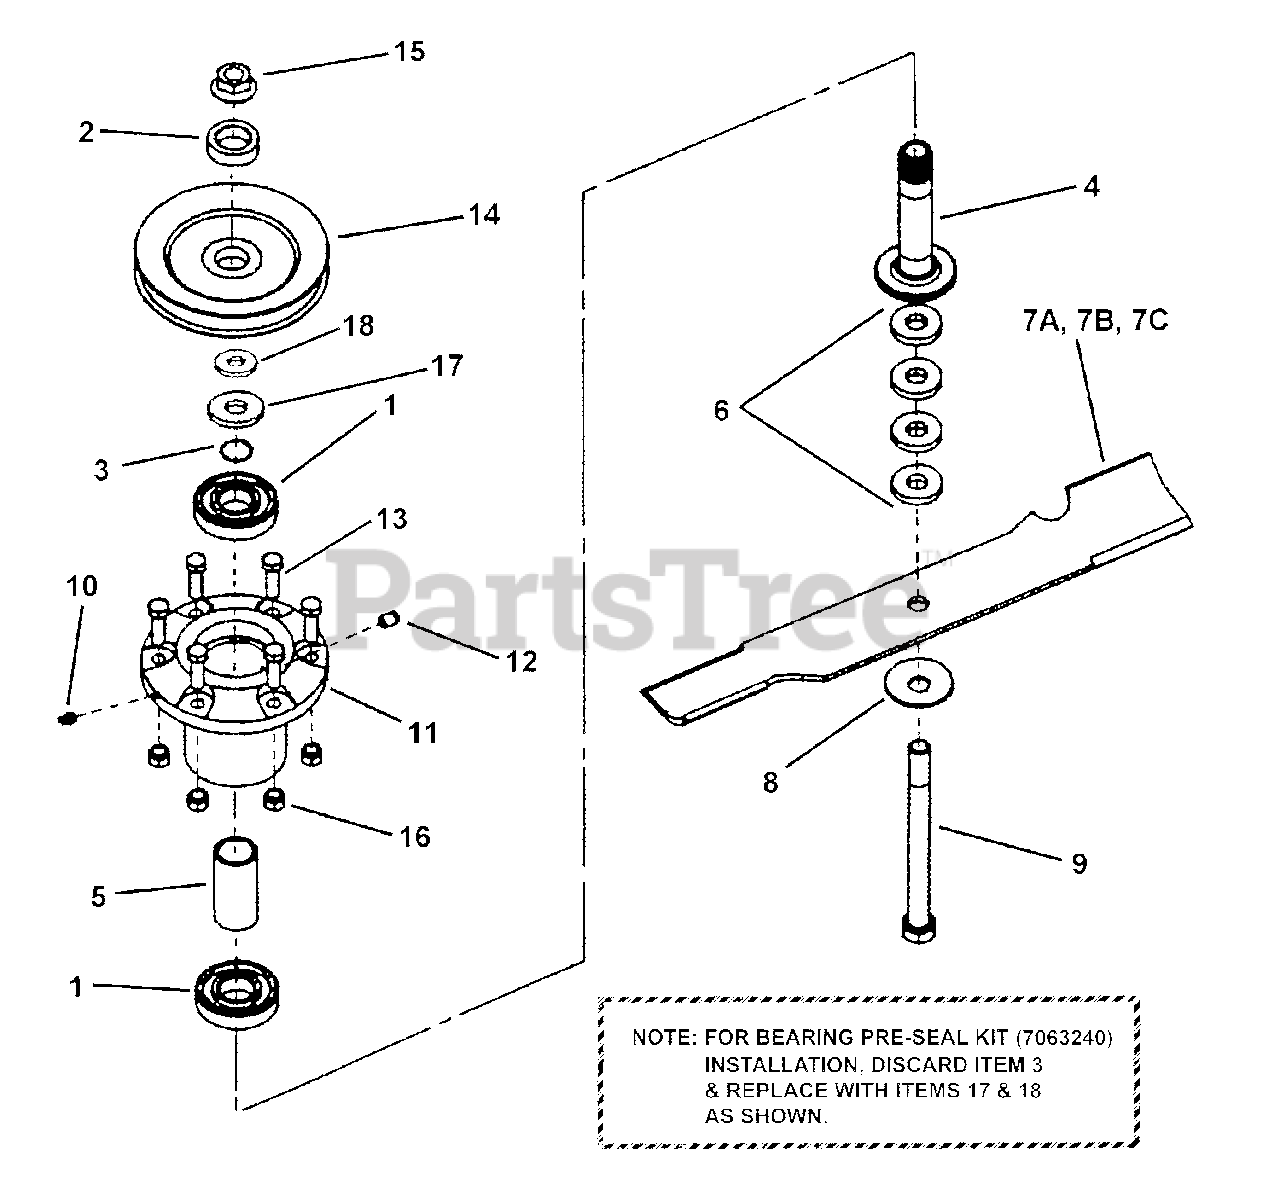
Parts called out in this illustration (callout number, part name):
1	BEARING, Sealed
2	WASHER, Spindle
3	SNAP-RING, Spindle Shaft
4	ASSEMBLY, Spindle Shaft
5	SPACER, Bearing
6	SPACER, Blade
7A	BLADE, Commercial, 18" Low Lift
7B	BLADE, 21" Low Lift
7C	BLADE, 16-1/2"
8	WASHER, Beveled
9	BOLT, 5/8-18 x 7-1/2" Hex Head Cap, GR 5
10	LUBE FITTING, 1/4-28 Straight (Thread Forming)
11	* HOUSING, Cutter
12	GREASE VENT, Spindle
13	BOLT, 3/8-16 x 1-1/4" Rib Necked
14	PULLEY, 5-3/4" O.D.
14	PULLEY, 5-3/4" O.D. w/Hub
15	NUT, 5/8-18 Hex Flange Lock, GR 5
16	NUT, 3/8-16 HEX NYLON LOCK
17	** SEAL, Nylos
18	** WASHER
